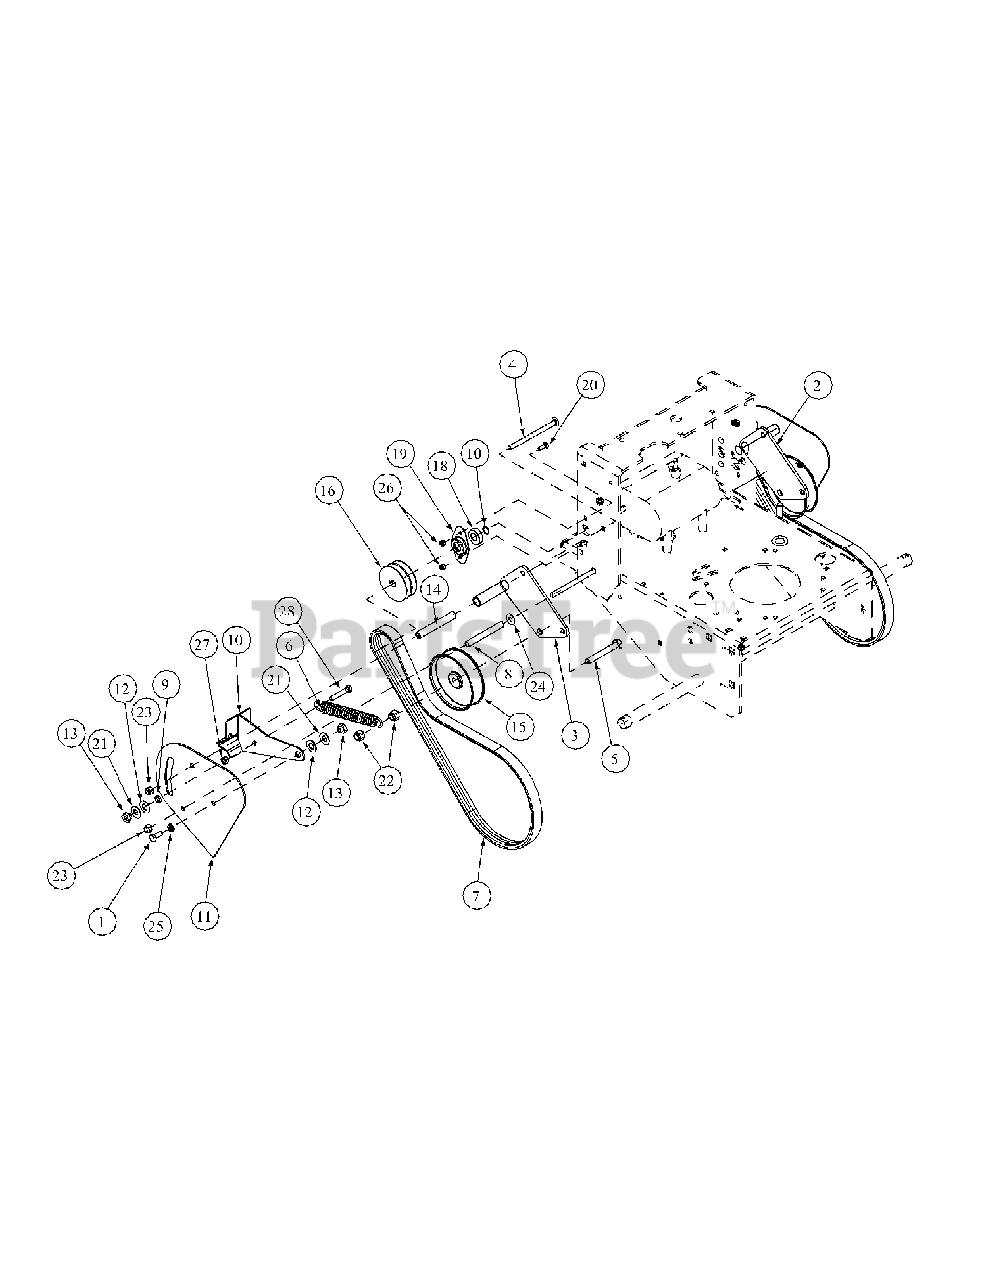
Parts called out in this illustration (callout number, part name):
1	Hex Cap Screw, 3/8-16, .875
2	Left Idler Bracket
3	Right Idler Bracket
4	Carriage Bolt, 3/8-16 x 5.50
5	Hex Cap Screw, 1/2-13, 3.50
6	Extension Spring
7	Belt, V
8	Spacer Tube
9	Roller Tube
10	Spring Adjust
11	Belt Guard
12	Slide Washer
13	Shoulder Nut
14	Idler Sleeve
15	Flat Idler Drive
16	Jackshaft Pulley
17	External Retain Ring
18	Bearing
19	Bearing Housing
20	Carriage Bolt, 1/4-20 x .750
21	Washer, 1/2 x 1
22	Lock Nut, Nylon Insert, 1/2-13
23	Lock Nut, Nylon Insert, 3/8-16
24	Flat Washer, 3/8 Zinc
25	Lock Washer, 3/8 Zinc
26	Lock Nut, Nylon Insert, 1/4-20
27	Hex Nut, 3/8-16
28	Hex Cap Screw, 3/8-16, 2.00
